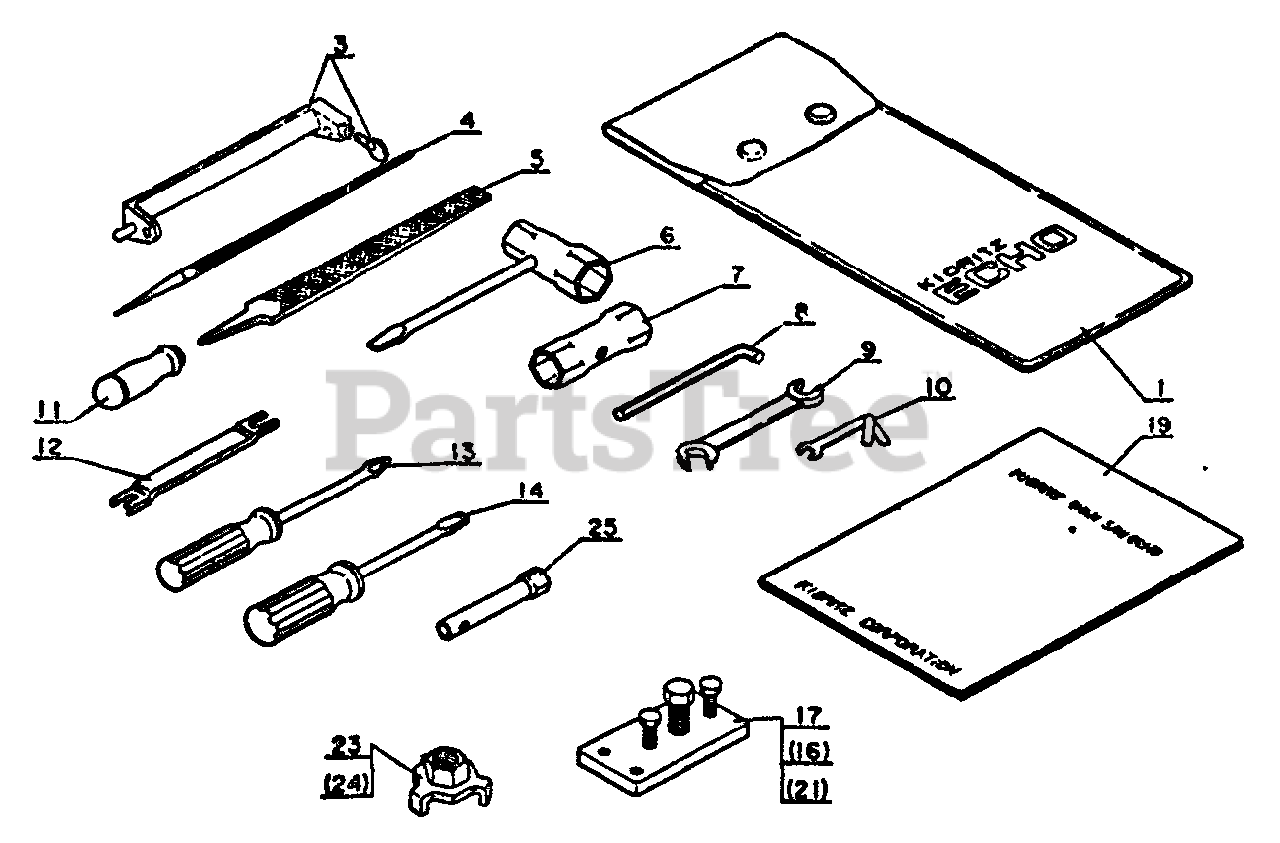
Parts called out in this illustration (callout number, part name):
1	BAG, TOOL
3	FILE HOLDER
4	ROUND FILE
5	FLAT FILE
6	T-WRENCH 13×19×180
7	BOX SPANNER - 14×17
8	WRENCH, ALLEN 4 MM
9	SPANNER - 8×10
10	MAGNETO SPANNER
11	FILE GRIP
12	GAUGE, DEPTH
13	SCREWDRIVER - CROSS HEAD
14	SCREWDRIVER, SLOTTED
17	MAGNETO PULLER
25	BOX SPANNER - 8
